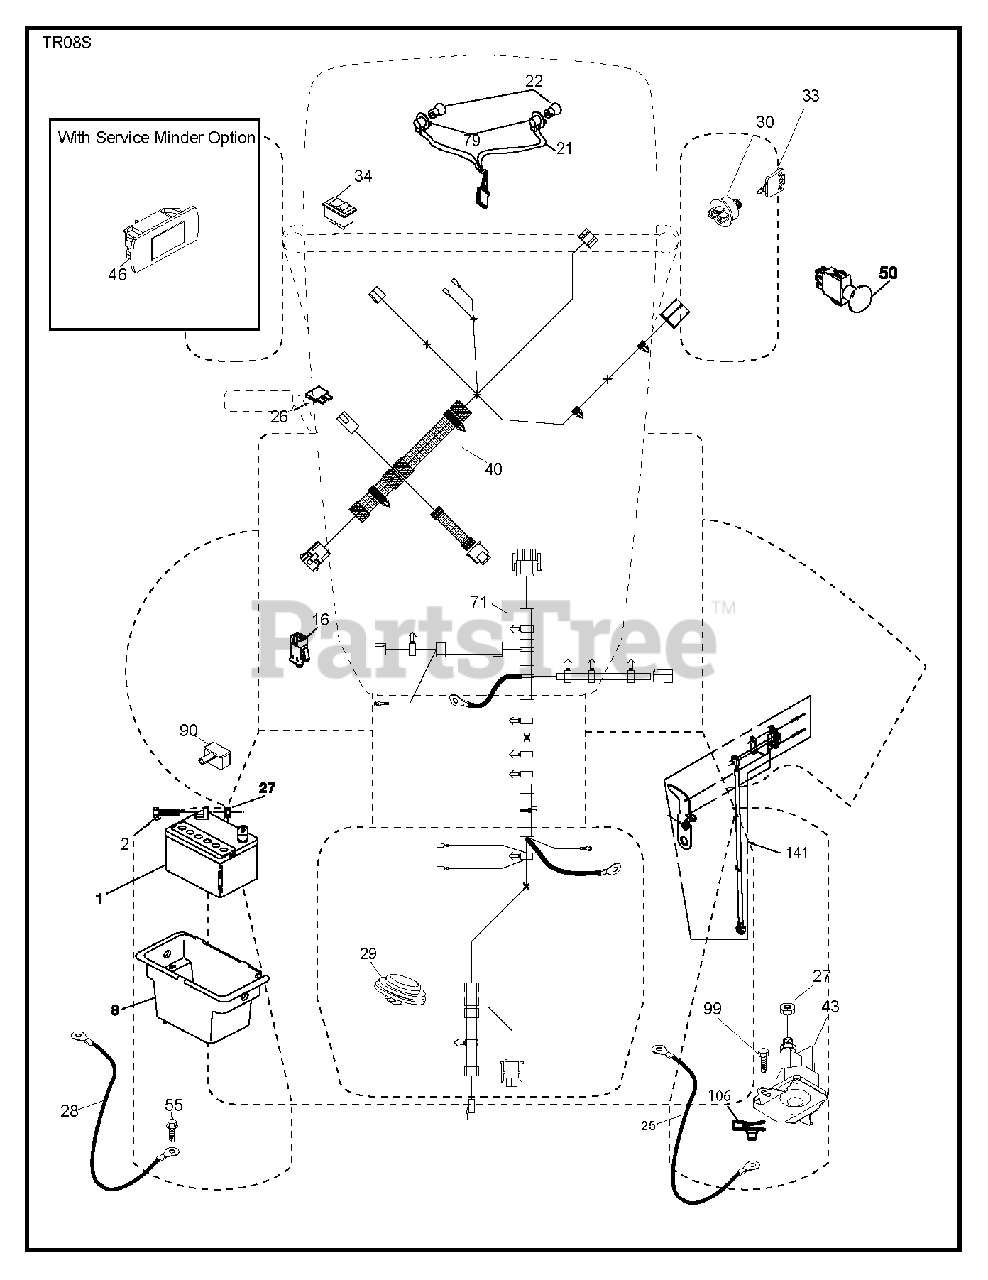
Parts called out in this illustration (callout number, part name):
8	BOX.BATTERY.MNT.REAR.L
16	SWITCH INTERLOOK PUSH-IN
21	HARNESS.LIGHT W/4152J BULBS
22	LIGHTBULB
25	CABLE.STARTER.6GA.BL/RED.14.
26	FUSE 20AMP
27	NUT
28	CABLE.BLACK.18"REAR.BA
29	SWITCH.SEAT.DELTA.OPC.
30	SWITCH.IGN.DELTA.W.LGH.ROS
33	KEY.CHAIN.BLISTER.PACK.GEN.INT
34	SWITCH LT
40	HARNESS.IGN.DASH.HUQ/P
43	SOLENOID.W/BRASS.PLUNG
46	GUAGE.SRVCMNDR.HRMTR.
50	PTO SWITCH
55	SCREW 5/16"
79	BULB HOLDER ASM.
90	COVER.TERMINAL.BATTERY
99	SCREW HEXWSHR 1/4-20X3/4
106	1/4-20 U NUT
141	KIT T2.ROS
